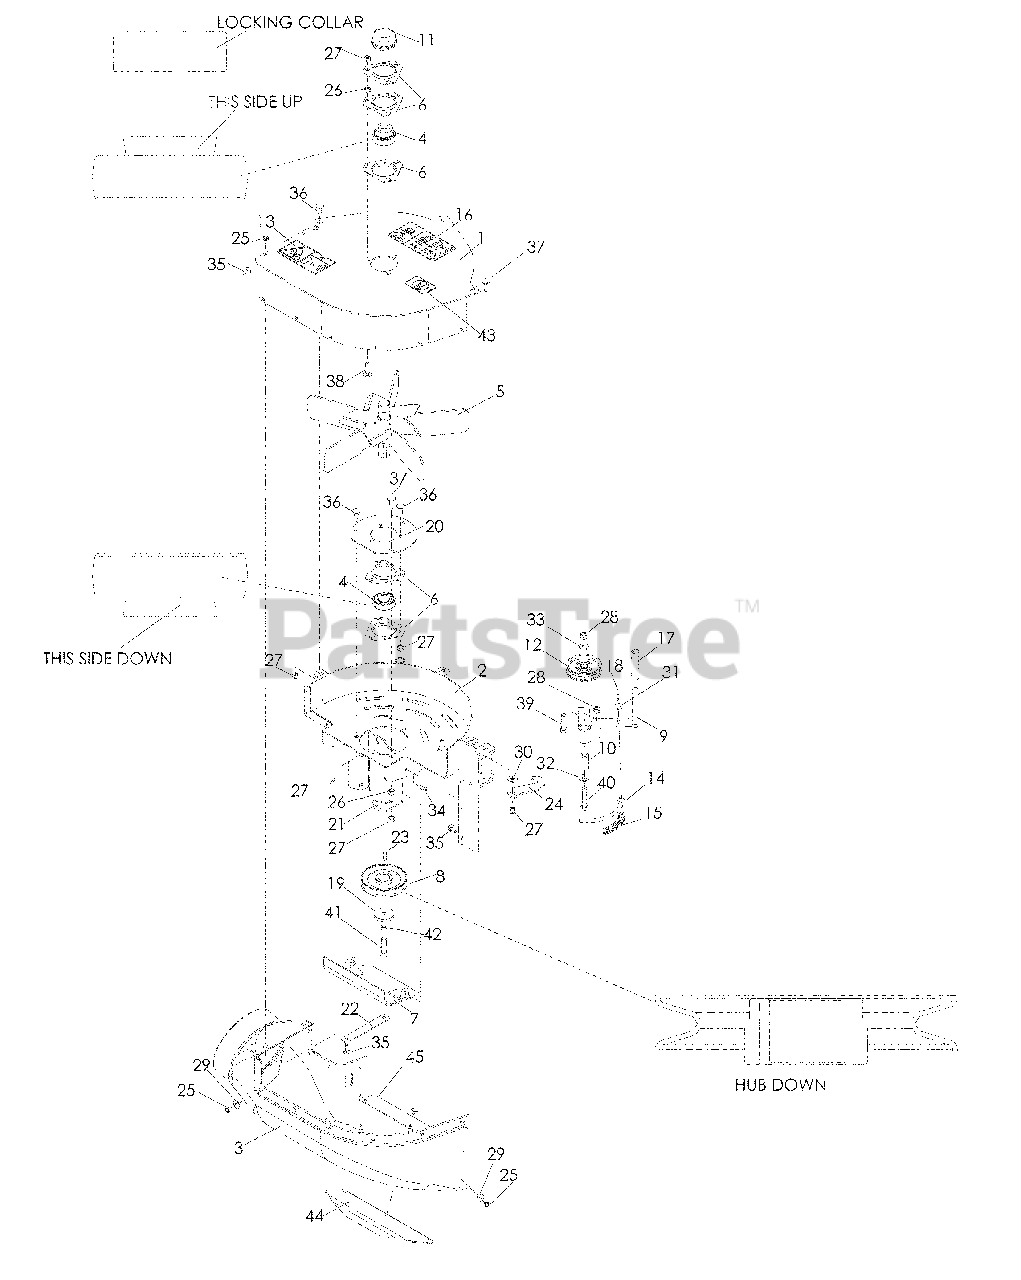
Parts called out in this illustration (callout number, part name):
1	FAN COVER W/DECALS
2	BLOWER HOUSING
3	LOWER HOUSING
7	COVER PLATE
10	SLEEVE BUSHING
11	GREASE CAP
13	DECAL, SEVERING
14	SPRING ROD
16	DECAL, WARNING
17	VINYL GRIP
18	PIN COTTER 3/32 x ¾
19	HEAVY WASHER
20	BEARING PLATE
21	BELT GUIDE
23	KEY ¼ SQ x ¾
24	IDLER ARM KEEPER
25	NUT ¼-20, THIN, NYLOC
26	NUT 5/16-18
27	NUT 5/16-18 NYLOC
28	NUT 3/8 -16 CENTERLOCK
30	WASHER 5/16
31	WASHER 5/16 SAE
32	WASHER 3/8
33	WASHER 3/8 SAE
34	SCREW ¼-20 x 5/8 BTN
35	RHSNB ¼-20 x ¾ GR2
36	RHSNB 5/16-18 x ¾
37	RHSNB 5/16-18 x 1
38	RHSNB 5/16-18 x 1¼
39	HCS 3/8-16 x 1½
40	HCS 3/8-16 x 2
41	HCS 7/16-20 x 1½
42	LOCKWASHER 7/16
43	DECAL, NO STEP
44	BLOWER SUPPORT
45	PLATE, BLOWOUT
